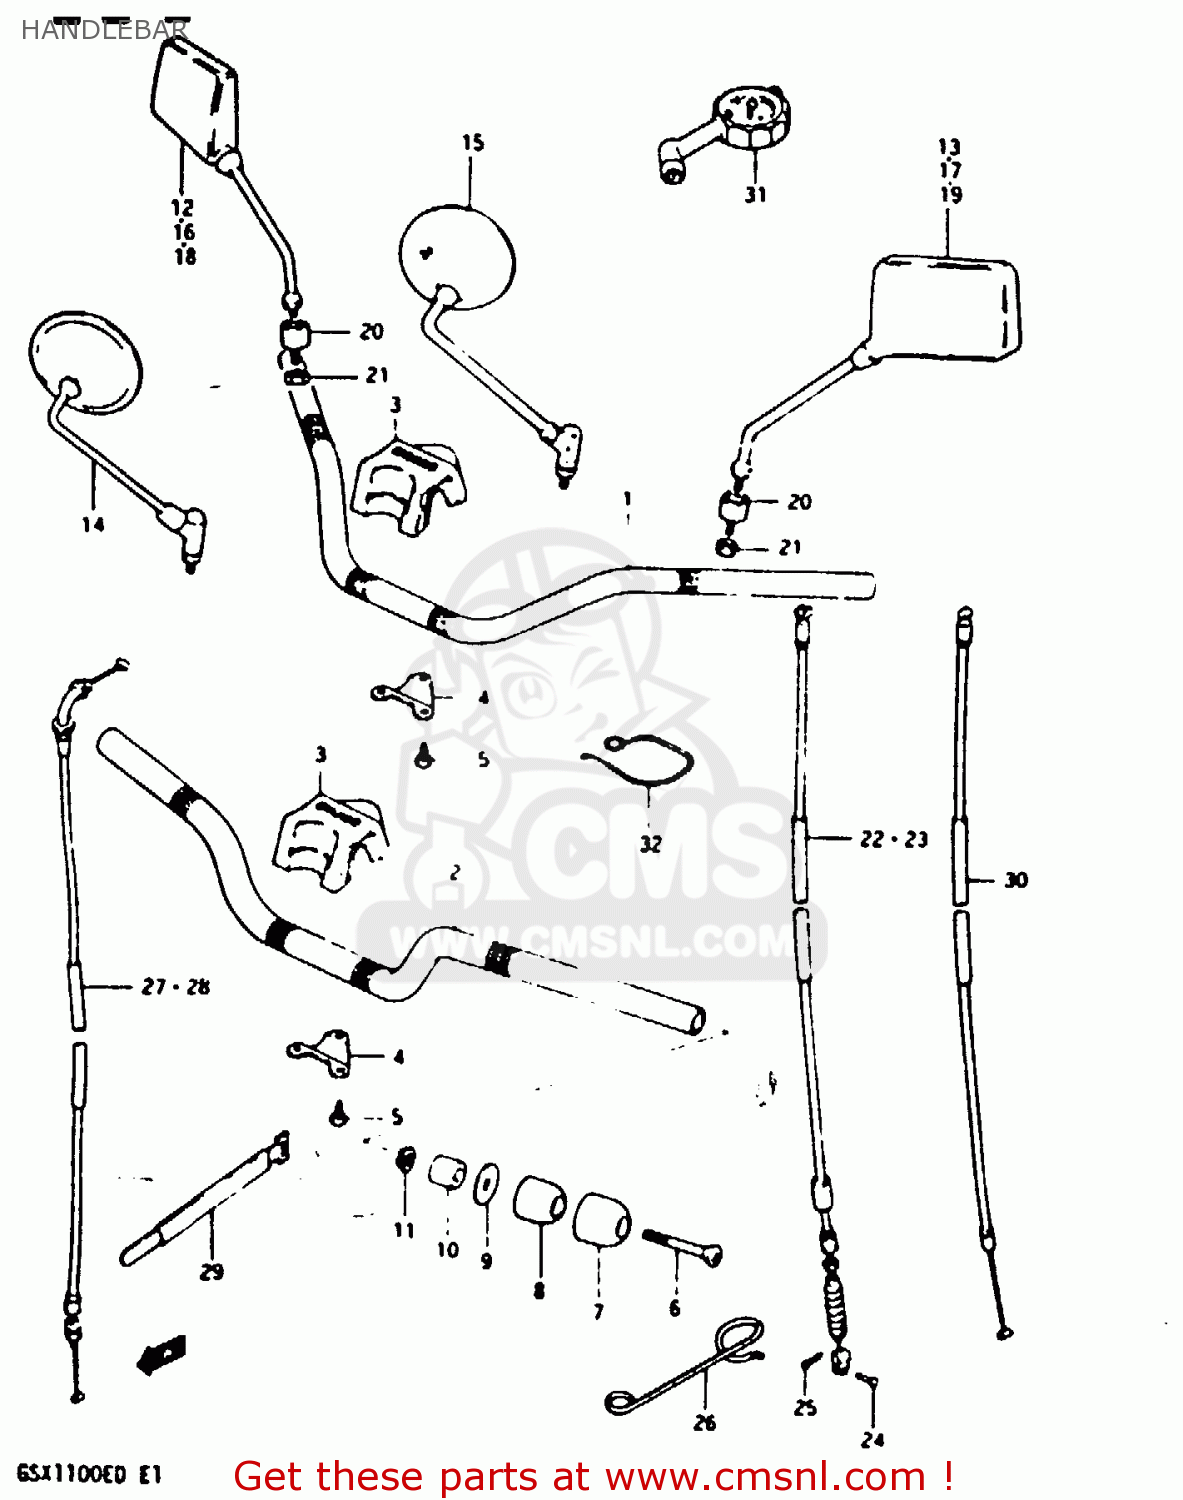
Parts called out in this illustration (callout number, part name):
1	HANDLEBAR
2	HANDLEBAR
3	COVER,STEERING HEAD
4	BRACKET,STEERING HEAD
5	SCREW
6	SCREW (FLAT TYPE)
7	CAP,BALANCER
8	BALANCER,HANDLEBAR
9	SPACER,BALANCER
10	EXPANDER,HANDLE BALANCER
11	NUT
14	MIRROR ASSY,RH
20	CUSHION,REAR VIEW MIRROR
21	NUT
22	CABLE ASSEMBLY,CLUTCH
23	CABLE ASSEMBLY,CLUTCH
24	PIN(L:15)
25	PIN
26	GUIDE,CLUTCH CABLE
27	CABLE ASSEMBLY,THROTTLE
28	CABLE ASSEMBLY,THROTTLE
29	CLAMP
30	CABLE ASSEMBLY,STARTER
31	GAUGE ASSY,AIR PRESSURE
32	GUIDE,CABLE/HARNESS
